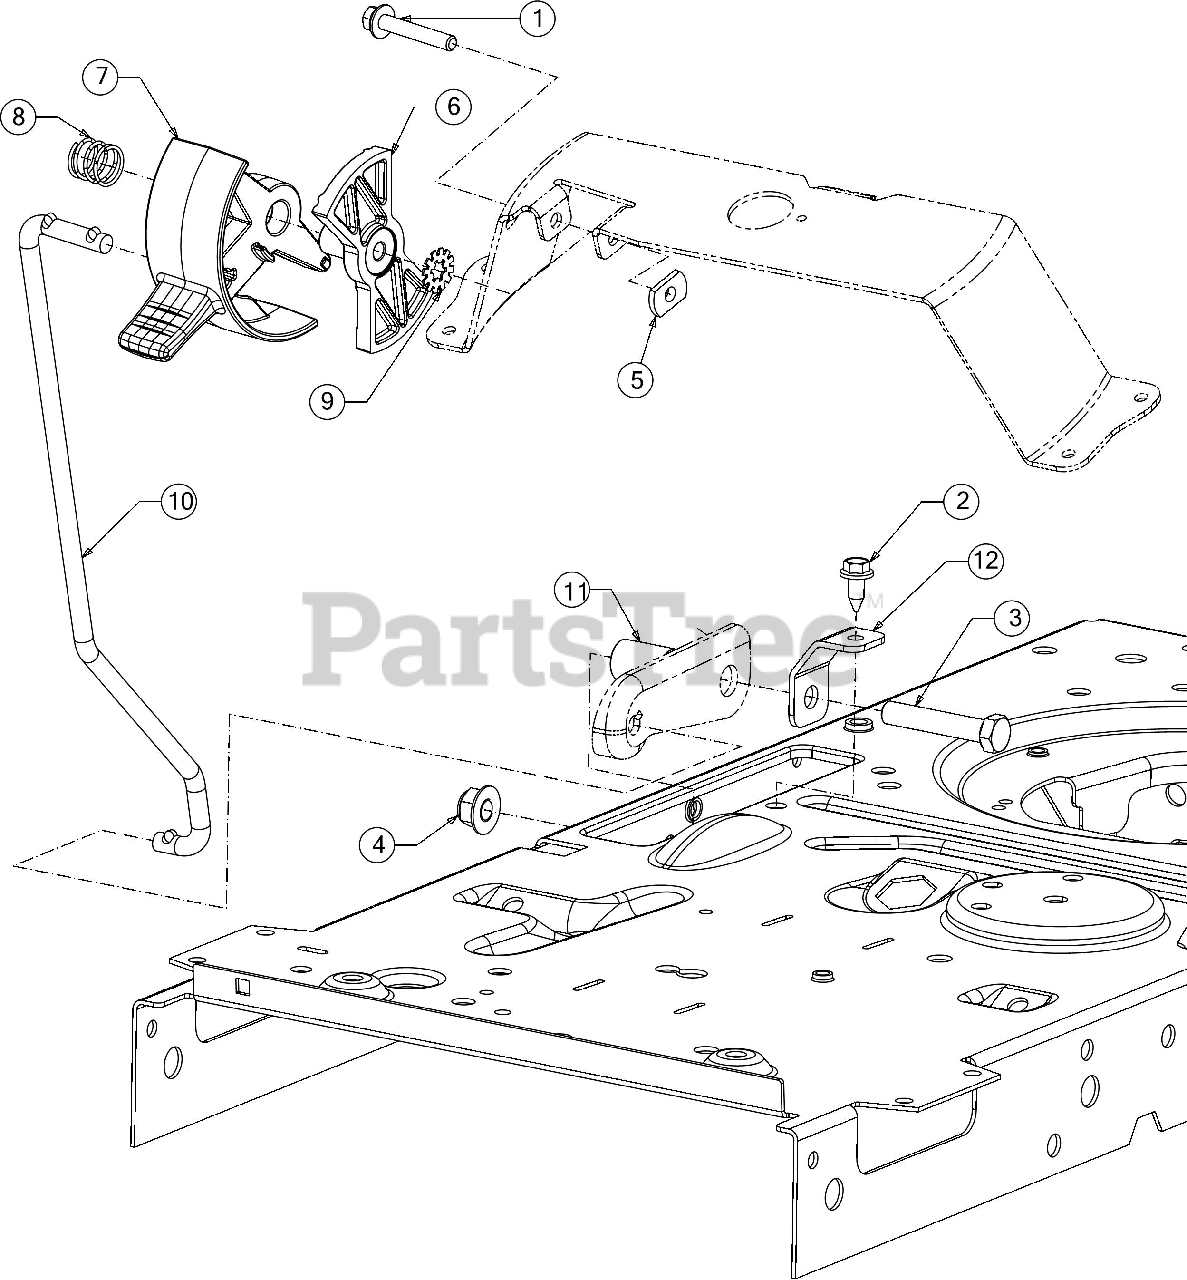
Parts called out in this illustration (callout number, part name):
1	SCREW 1/4-20 X 1.50 GR5
2	SCREW 1/4-20X.625
3	SCREW 3/8-16 X 2.0 GR5
5	FLAT NUT
6	PARK INDEX CONTROL
7	SHIFT LEVER
8	COMPRESSION SPRING
9	WASHER
10	SPEED CONTROL ROD
11	FLANGE SPACER
12	SPEED LATCH TAB
